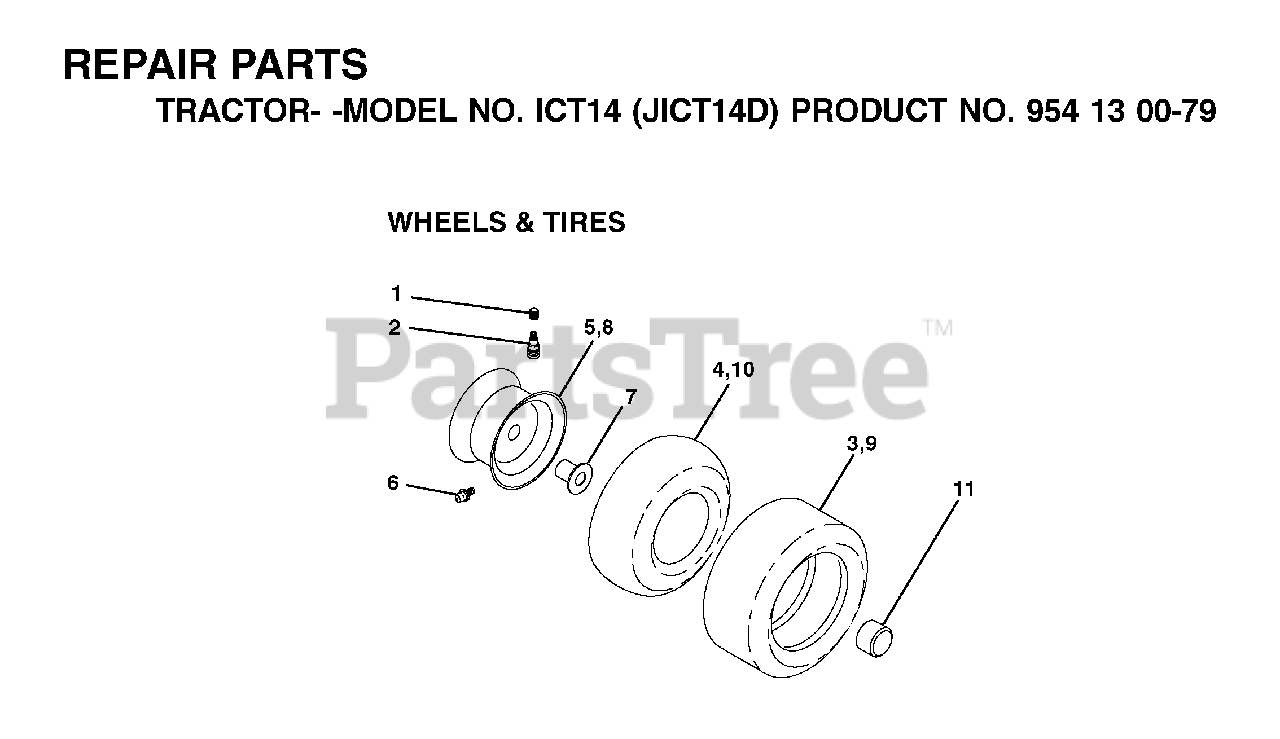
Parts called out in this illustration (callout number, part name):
1	VALVE CAP
2	VALVE STEM LT
3	TIRE HEAVY DUTY
4	TUBE.5.3/4.5/6
5	RIM ASM 6" FRONT SILVER
6	FITTING LT
7	BEARING T
8	RIM ASM 8" REAR SILVER
9	TIRE
10	TUBE
11	CAP, AXLE BLK
